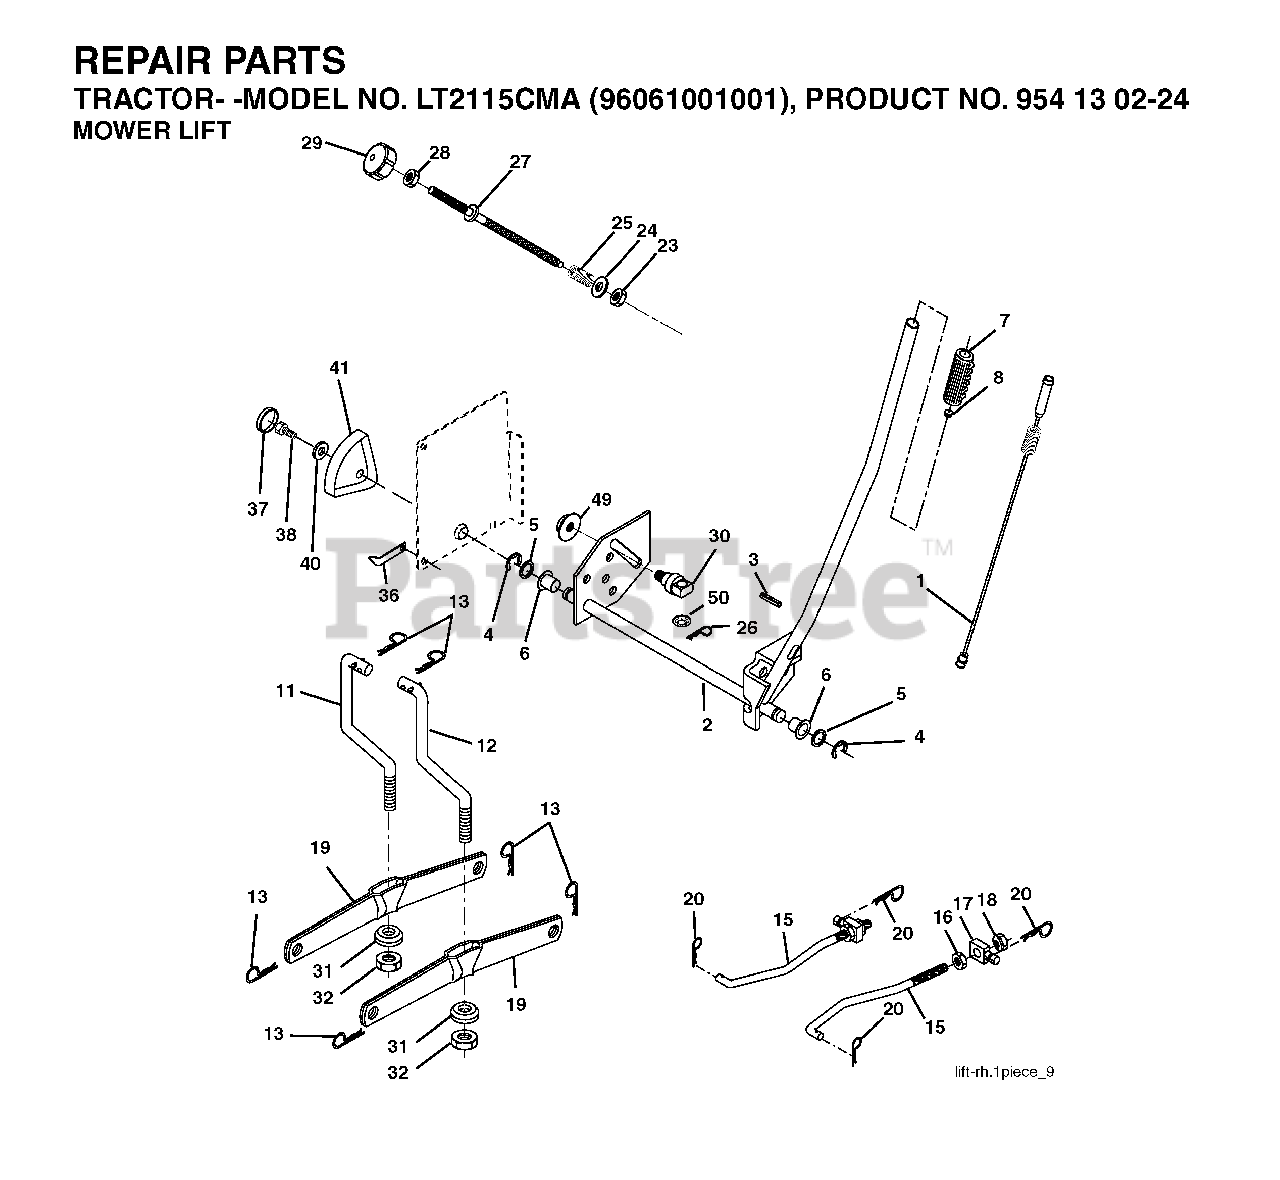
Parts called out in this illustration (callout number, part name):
1	WIRE, INNER
4	RETAINING RING LT
6	BEARING.NYLON
7	GRIP HANDLE
8	PLUNGER BUT KIT
11	LINK
12	LINK
13	RETAINER-SPRNG RB
15	LINK.SUSPENSION.FRONT
16	NUT
18	NUT
19	ARM.REAR.SUSPENSION
20	SPRING RETAINER
25	SPRING**
26	RETAINER CLIP
27	ROD ADJ LIFT
28	NUT
29	KNOB INF 3/8-16
31	BEARING.PIVOT.LIFT
32	NUT CROWNLOCK 3/8-24
36	POINTER, HEIGHT INDICATOR
37	PLUG,HOLE
38	SCREW 5/16-18X1
41	HEIGHT INDICATOR
49	NUT
50	NUT PUSH M
